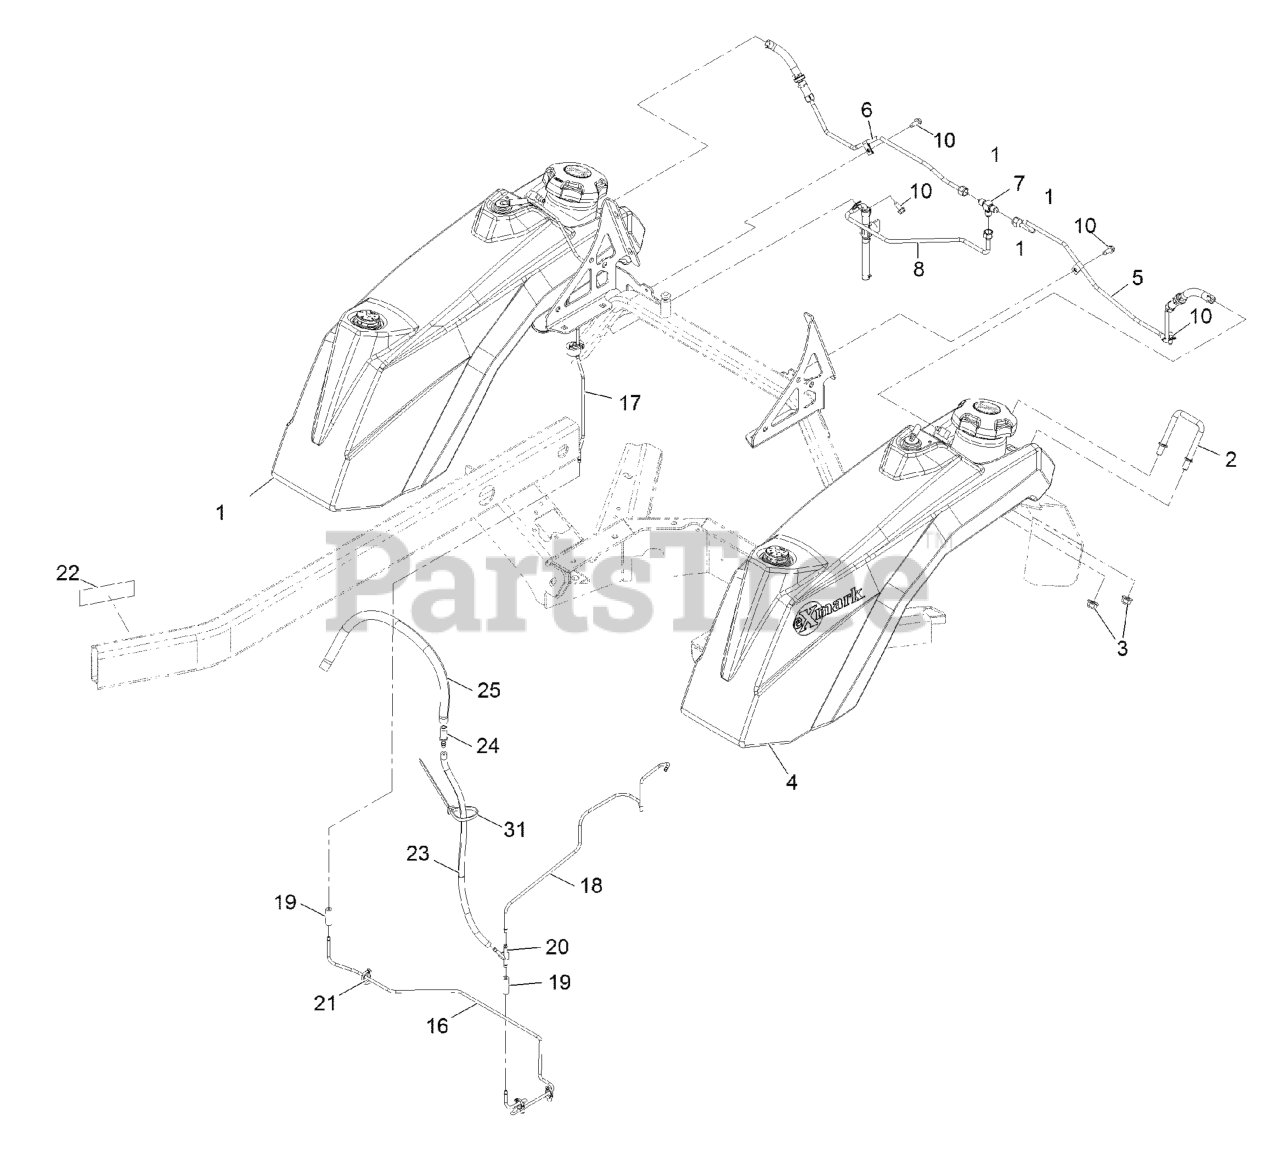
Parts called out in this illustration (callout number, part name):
1	ASM, Rt Fuel Tank
2	Clamp, Tank
4	ASM, Lt Fuel Tank
5	ASM, Left Fuel Line
6	ASM, Right Fuel Line
7	Fitting, 2603-4-4-4
8	ASM, Kaw Fuel Line
10	SCREW-HWH
16	Line, Vent, Main
17	Line, Vent, Right
18	Line, Vent, Left
19	HOSE-FUEL
20	Fitting, 3/16" Y
21	CLIP-TIE
22	DECAL-ARRESTOR, SPARK
23	Hose, Vent
24	FITTING-STRAIGHT
25	HOSE-FUEL
31	TIE-PLASTIC
